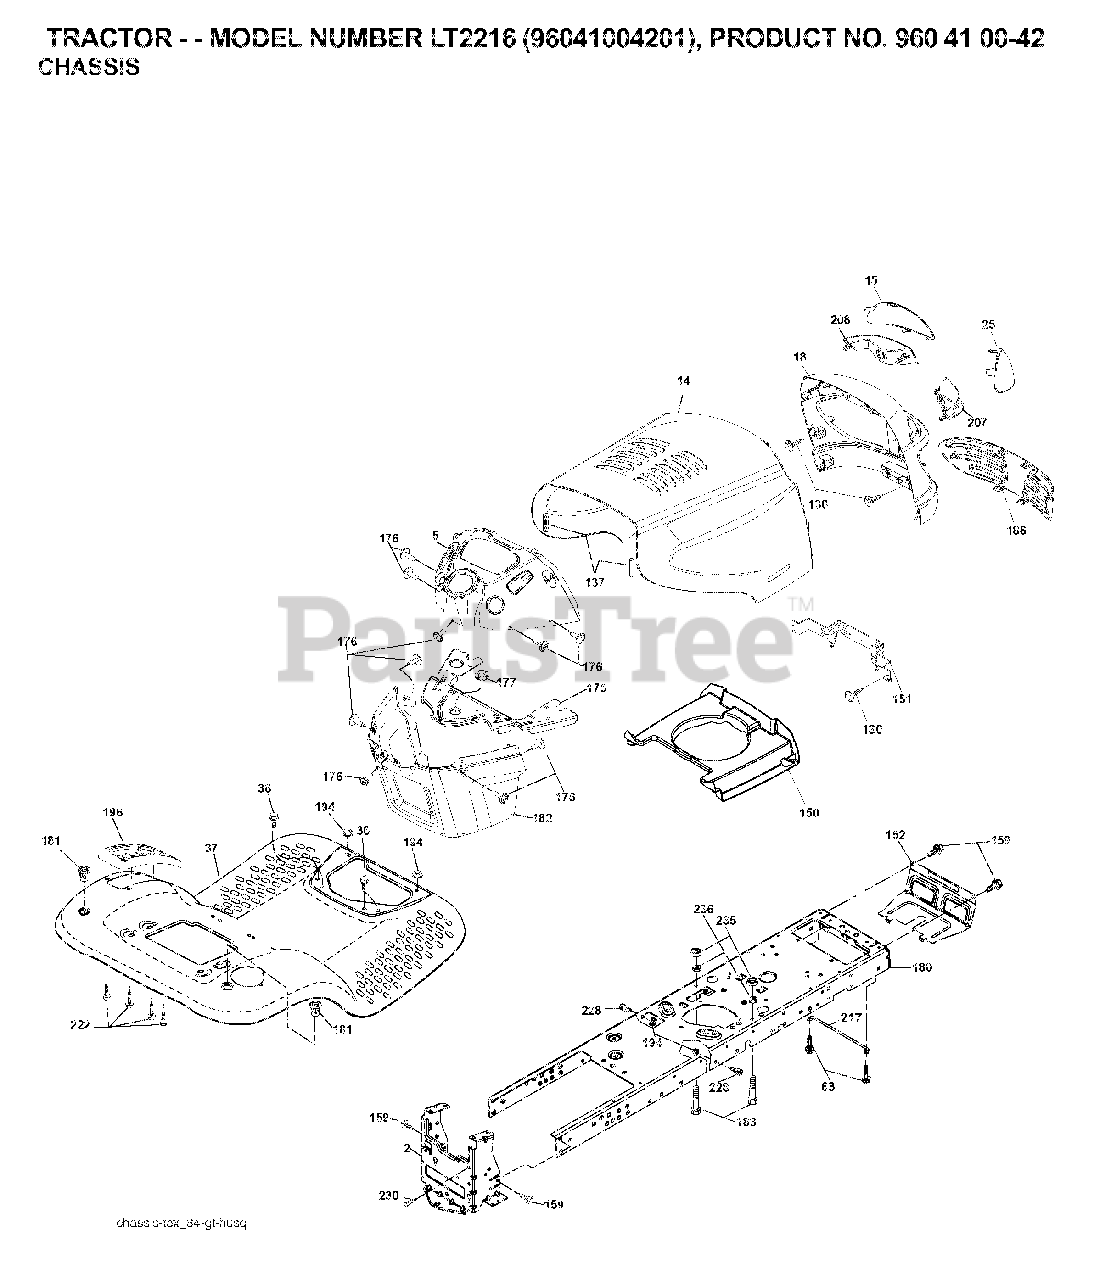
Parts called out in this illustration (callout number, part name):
2	DRAWBAR.1PC.NSTL
34	PLATE.ENGINE.WELDED.CHASSIS
36	SCREW 3/8-16X3/4
52	LOCKNUT
130	SCREW
137	BUMPER.HOOD.LARGE.1.75"
151	BRACKET PIVOT
152	SHIELD.BROWNING/DEBRIS
159	SCREW, 3/8-16X3/4
175	CROSSMEMBER.LT
176	SCREW.#10-24X5/8.RN.QU
177	BUSHING STEERING
180	CHASSIS.STAMPING.LT/GT
181	FEND/FTRST.PCH.CPH.NFW
182	DASH.LOWER.LT.CCS
183	BOLT.5/16-18X1-1/4 FULL.THREAD
189	SCREW
194	NUT LOCK HEX FLANGE 5/16-18
196	CONSOLE.ASM.DECK.LIFT.TLT.BLAC
207	BEZEL GRILL RH
208	BEZEL GRILL LH
217	ROD PIVOT CHASSIS/HOOD
222	SCREW.1/4-20X5/8
228	STUD.FASTNER.W/ANTI-ROTATE
230	SHOULDER BOLT 5/16-18TT
235	SPACER FENDER
236	NUT.CENTERLOCK.5/16-
